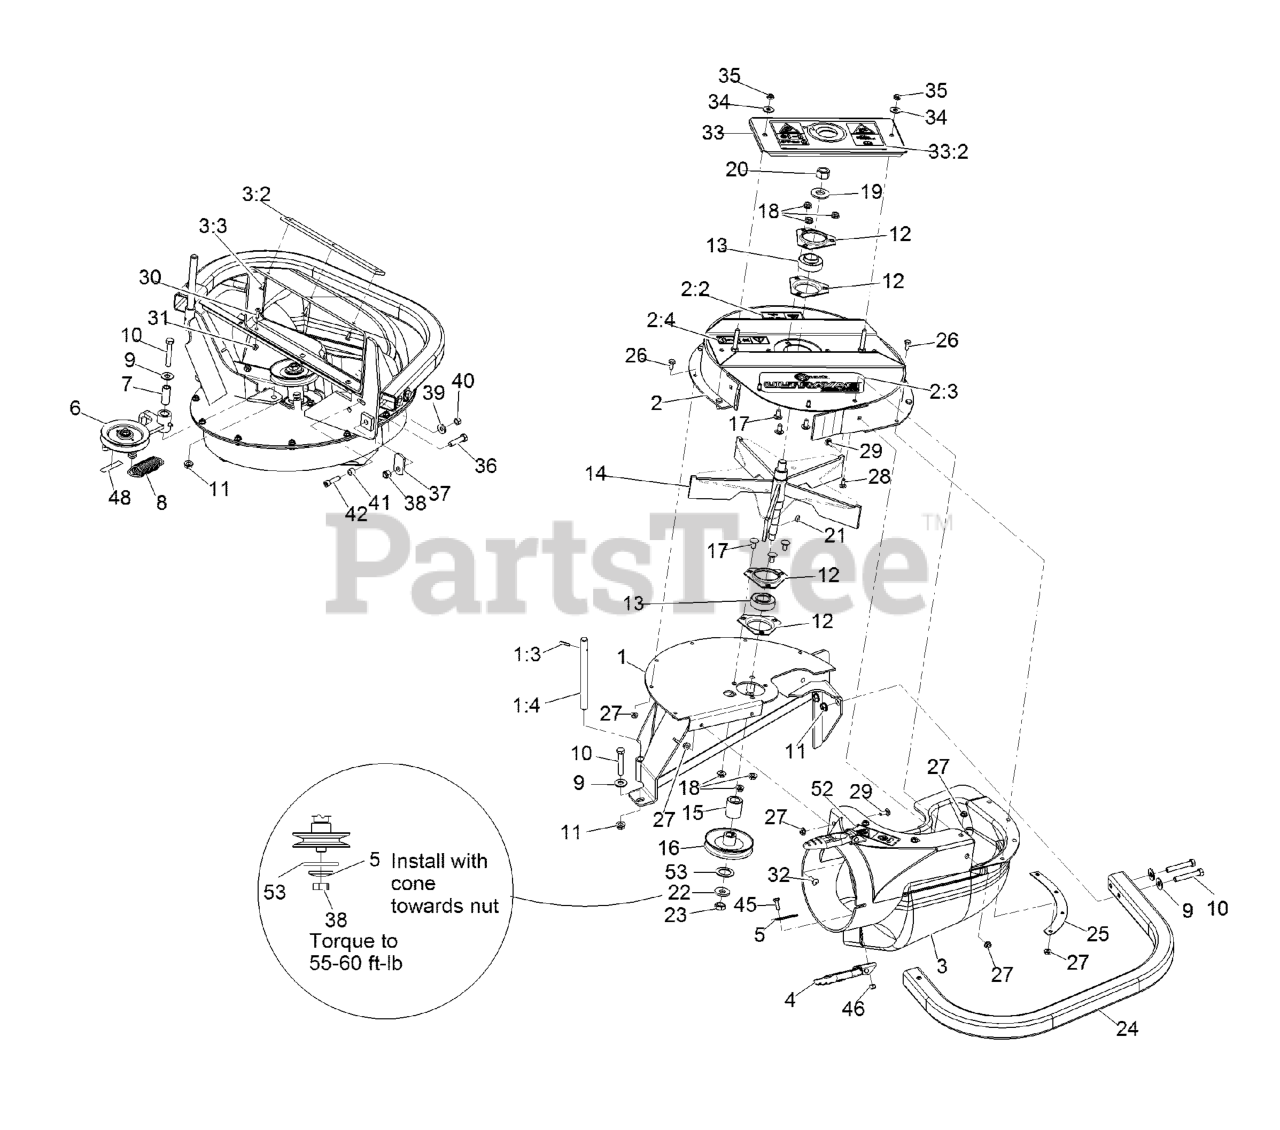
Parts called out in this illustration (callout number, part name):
1	WLD,FRAME LG BLOWER
1:3	PIN-ROLL
1:4	SHAFT-CATCHER, GRASS
2	ASM-UPPER HOUSING LARGE
2:2	DECAL-WARNING, TRACTION
2:3	Decal-Ultravac X-Series
2:4	DECAL-COVER, MISSING
3	ASM,BLOWER CHUTE LZ
3:2	PLATE,REINFORCEMENT LARGE
3:3	RIVET-BLIND
4	LATCH-RUBBER
5	PLATE-BACKING
6	ASM, Idler
7	BUSHING
8	SPRING-IDLER
9	WASHER-FLAT
10	SCREW-HH
11	NUT-HHF, WHIZ
12	HOUSING-FLANGE
13	BEARING
14	IMPELLER
16	SHEAVE
17	SCREW-CARR
19	WASHER-SPRING
20	NUT-HEX
21	KEY-WOODRUFF
22	WASHER-SPRING
23	NUT-JAM
25	PLATE-BACKING, BLOWER
26	SCREW-HH
28	SCREW-CARR
29	BOLT-CARR
30	SCREW-HEAD, TRUSS
33	ASM, BEARING COVER
33	COVER, BEARING
33:2	DECAL-WARNING, BLOWER
34	WASHER-FLAT
35	NUT-LOCK, NI
36	SCREW-HH
37	LATCH-CATCHER, GRASS
38	NUT-LOCK, NI
39	WASHER-SPRING
40	NUT-HEX
41	BUSHING, LOCATOR
42	SCREW-HSH
45	SCREW-HH
46	NUT-LOCK, NI
48	DECAL-WARNING
52	Decal-Blower-Impeller Hazard
53	WASHER-SPACER
